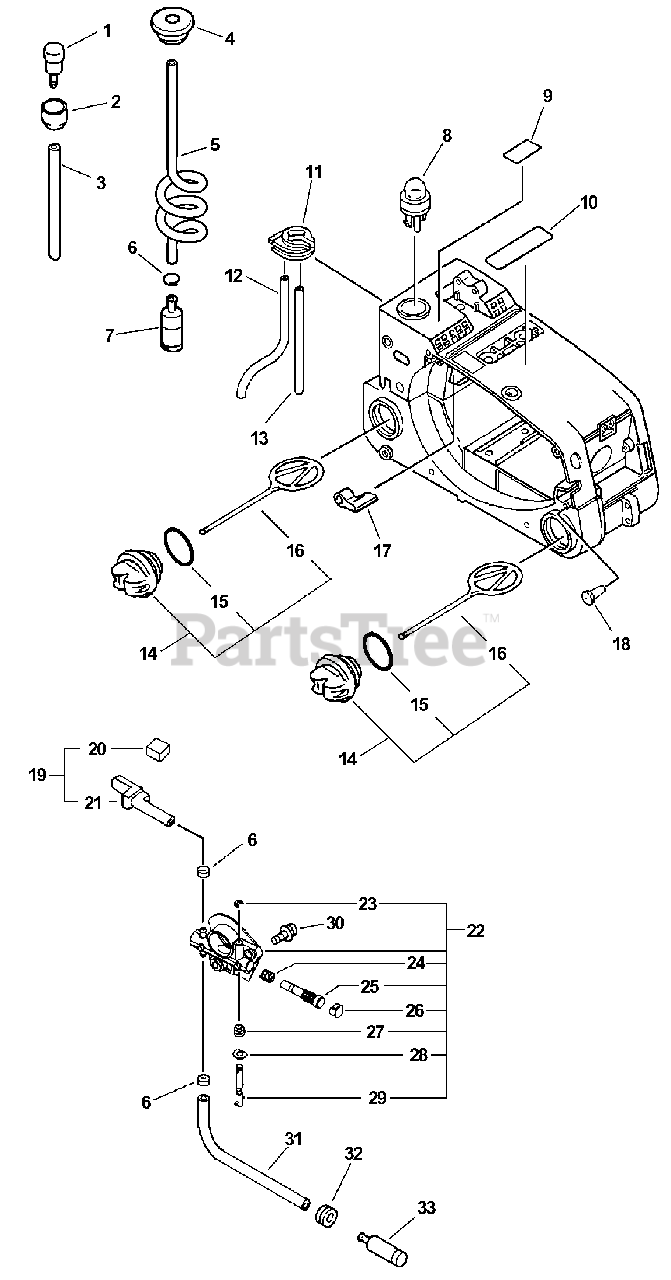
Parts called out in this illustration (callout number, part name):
1	VENT, FUEL TANK
2	HOLDER, VENT
3	PIPE - 3X5X100 -- BLACK
4	GROMMET
5	PIPE, FUEL - SPIRAL
6	CLIP - 6.5
7	FILTER, FUEL
8	PUMP, PURGE
9	LABEL - PURGE PUMP
10	LABEL - CAUTION
12	PIPE - 2X4X42 -- CLEAR
13	PIPE - 3X5X70 -- BLACK
14	CAP ASSY - ORANGE
15	O-RING - 25
16	CONNECTOR, CAP
18	VENT, TANK
19	OIL PIPE KIT
20	PAD, FOAM
21	PIPE - OIL
22	AUTO-OILER ASSY
23	RING, RETAINING
24	SPRING, PLUNGER
25	PLUNGER ASSY
26	CAP, OIL PUMP
29	NEEDLE, ADJUST
30	SCREW - 5X12
31	PIPE - 3X6X115 -- BLACK
32	GROMMET
33	FILTER, OIL
